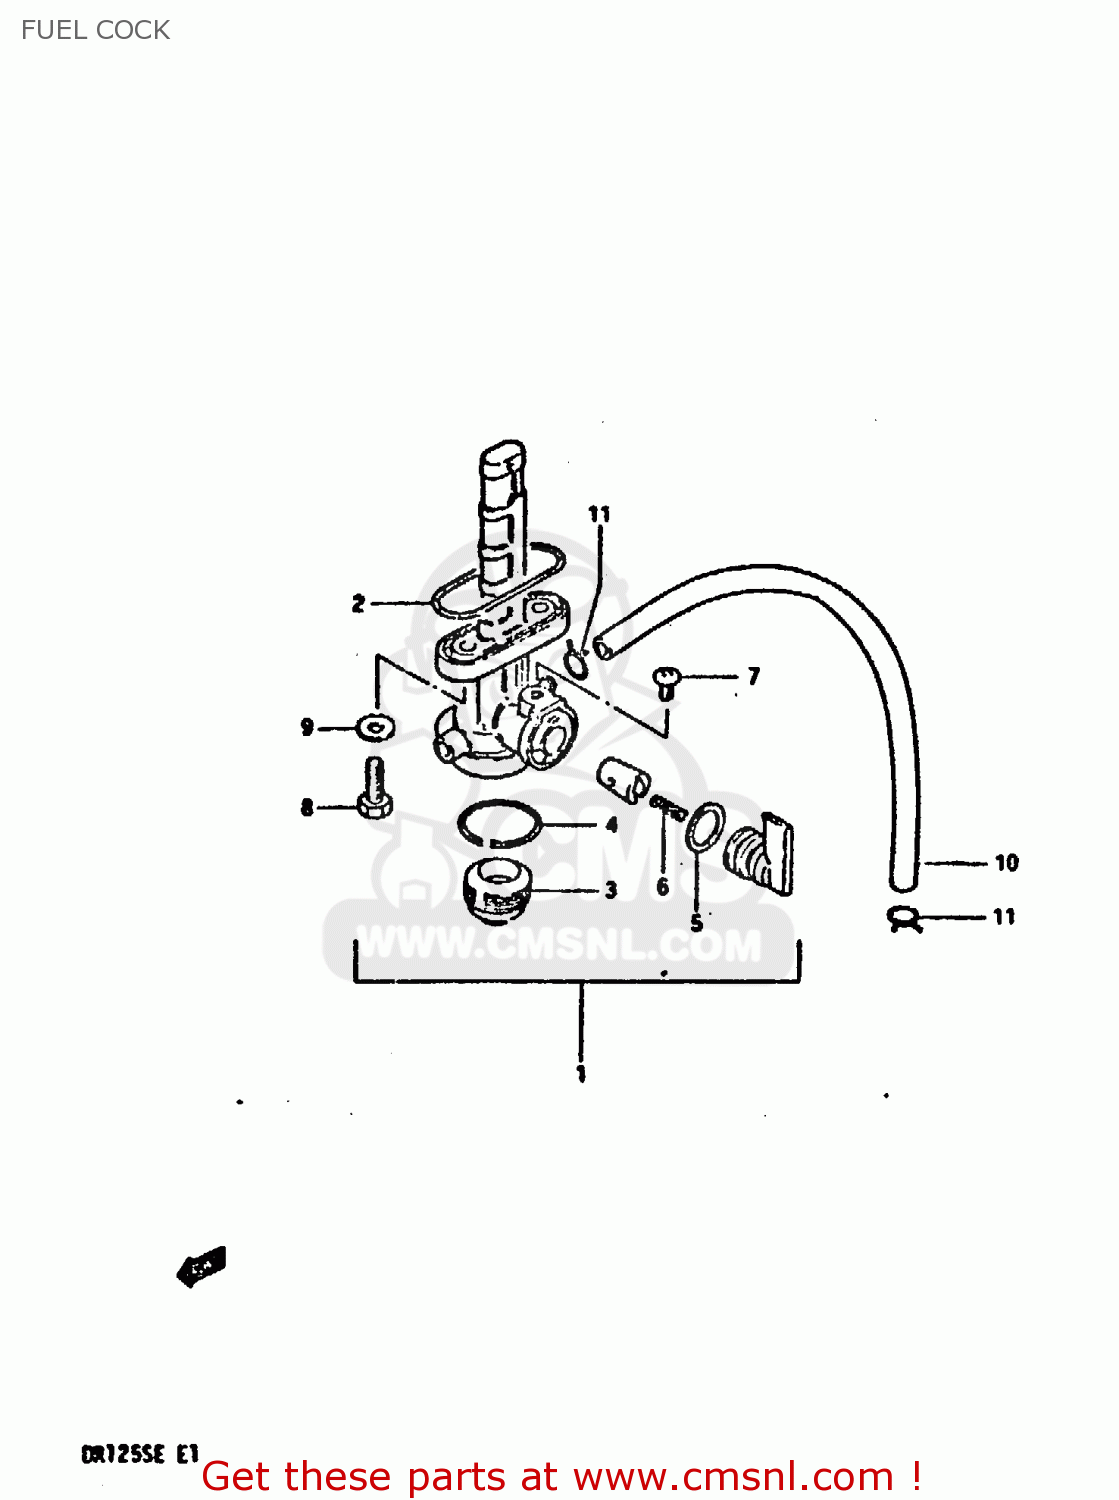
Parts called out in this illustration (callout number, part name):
1	COCK ASSEMBLY,FUEL
2	O RING,FUEL COCK
3	CUP,STRAINER
4	GASKET,FILTER (NAS)
5	O-RING
6	SPRING
7	SCREW
8	BOLT(6X20)
9	GASKET
10	HOSE
11	CLIP
